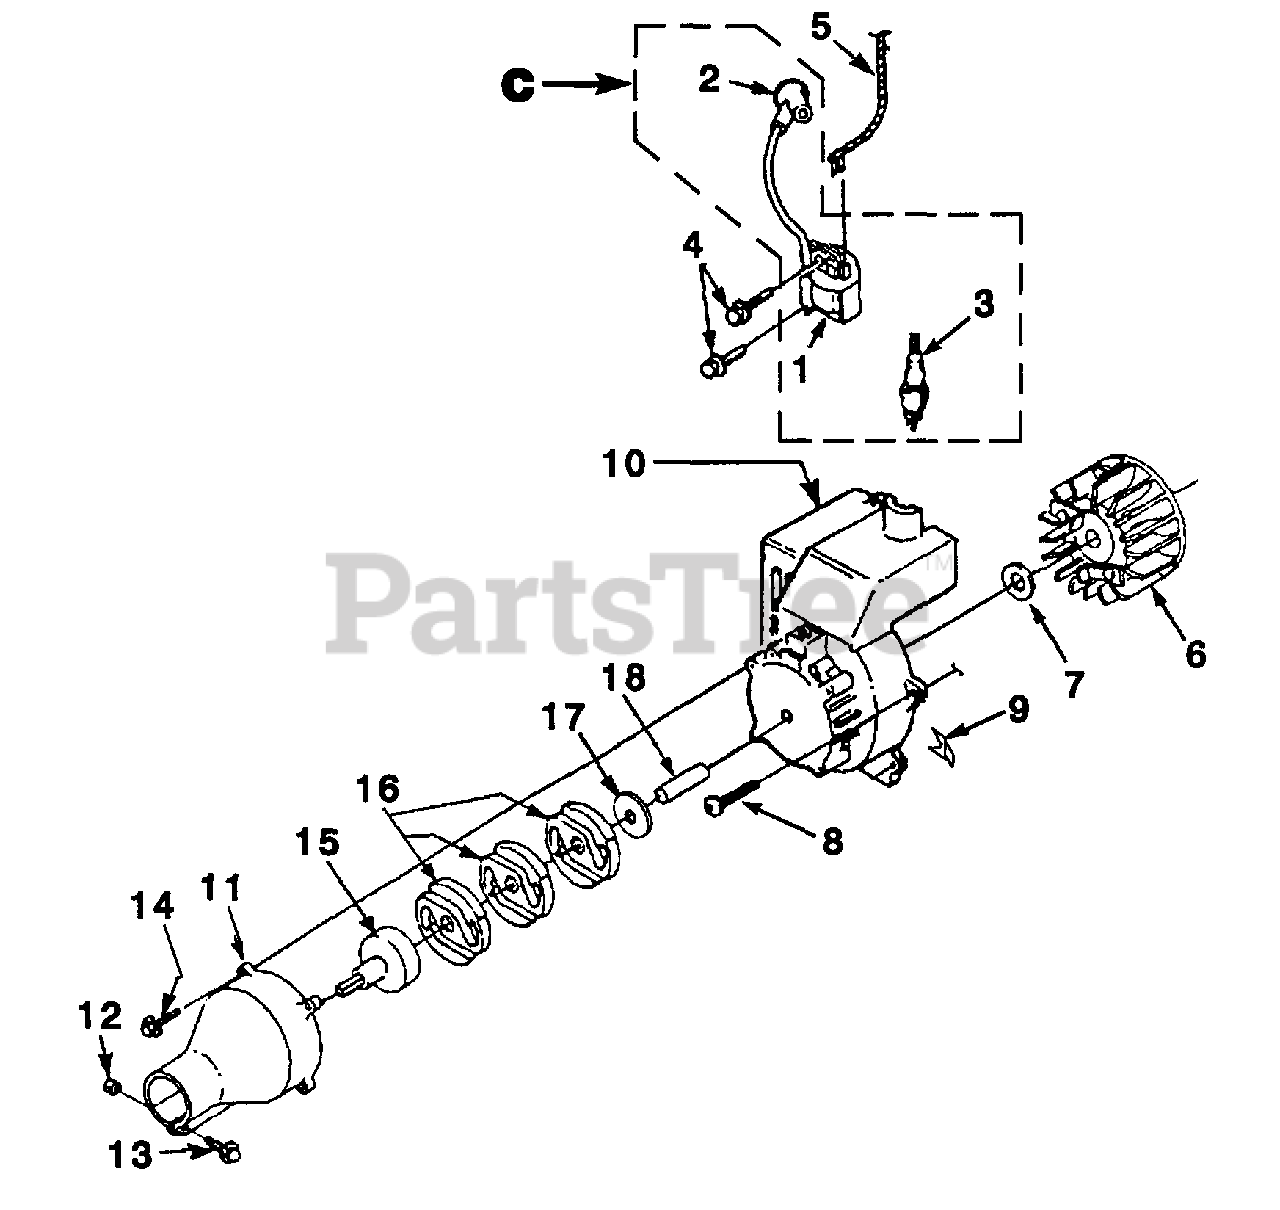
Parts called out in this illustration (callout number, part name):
1	MODULE-Ignition
2	TERMINAL & COVER
3	SPARK PLUG (DJ-7Y)
4	SCREW-Thread Form. (8-32 X 1")
5	LEAD-Electrical
6	ROTOR & STARTER PAWL
7	WASHER-Flat
8	SCREW-Thread Form. (10-24 X 3/4")
9	TAB-Male
10	HOUSING-Engine w/Decals
11	TUBE ADAPTOR KIT
12	NUT-Hex (10-24)
13	SCREW-Sems Hex Hd. (10-24 X 1 1/4")
14	SCREW-Sems Hex Hd. (10-24 X 7/8")
15	DRUM & CONNECTOR
16	CLUTCH
17	WASHER-Clutch
18	SPACER
C	IGNITION KIT
